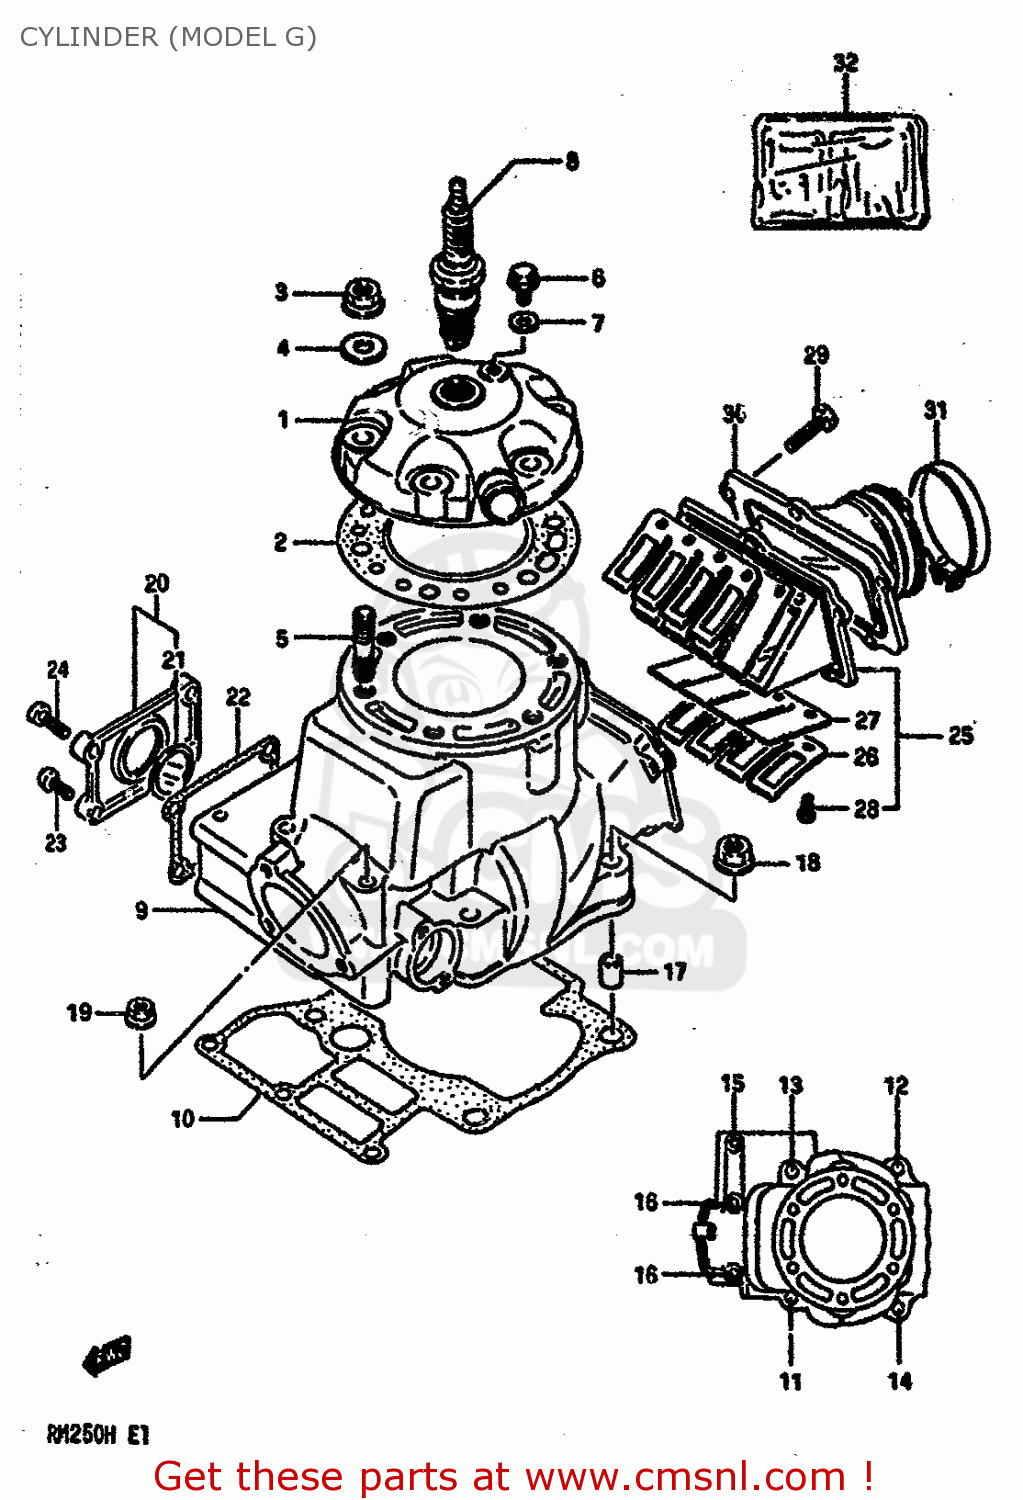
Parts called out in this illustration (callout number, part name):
1	HEAD,CYLINDER
2	GASKET,CYLINDER HEAD (MCA)
3	NUT
4	WASHER
5	BOLT,STUD
6	UNION
7	GASKET(6.2X11X1).2 (NAS)
8	PLUG,SPARK(NGK B-8EN)
9	CYLINDER
10	GASKET,CYLINDER (NAS)
11	BOLT,STUD
12	BOLT,STUD
13	BOLT,STUD
14	BOLT,STUD
15	STUD BOLT
16	STUD BOLT
17	PIN
18	NUT
19	NUT
20	COVER,CYLINDER
21	LENS,CYLINDER COVER
22	GASKET,CYLINDER COVER (MCA)
23	SCREW
24	SCREW
25	VALVE ASSEMBLY,REED
26	STOPPER,REED VALVE
27	VALVE,REED
28	SCREW
29	BOLT
30	PIPE,INTAKE
31	CLAMP
32	GASKET SET (MCA)
